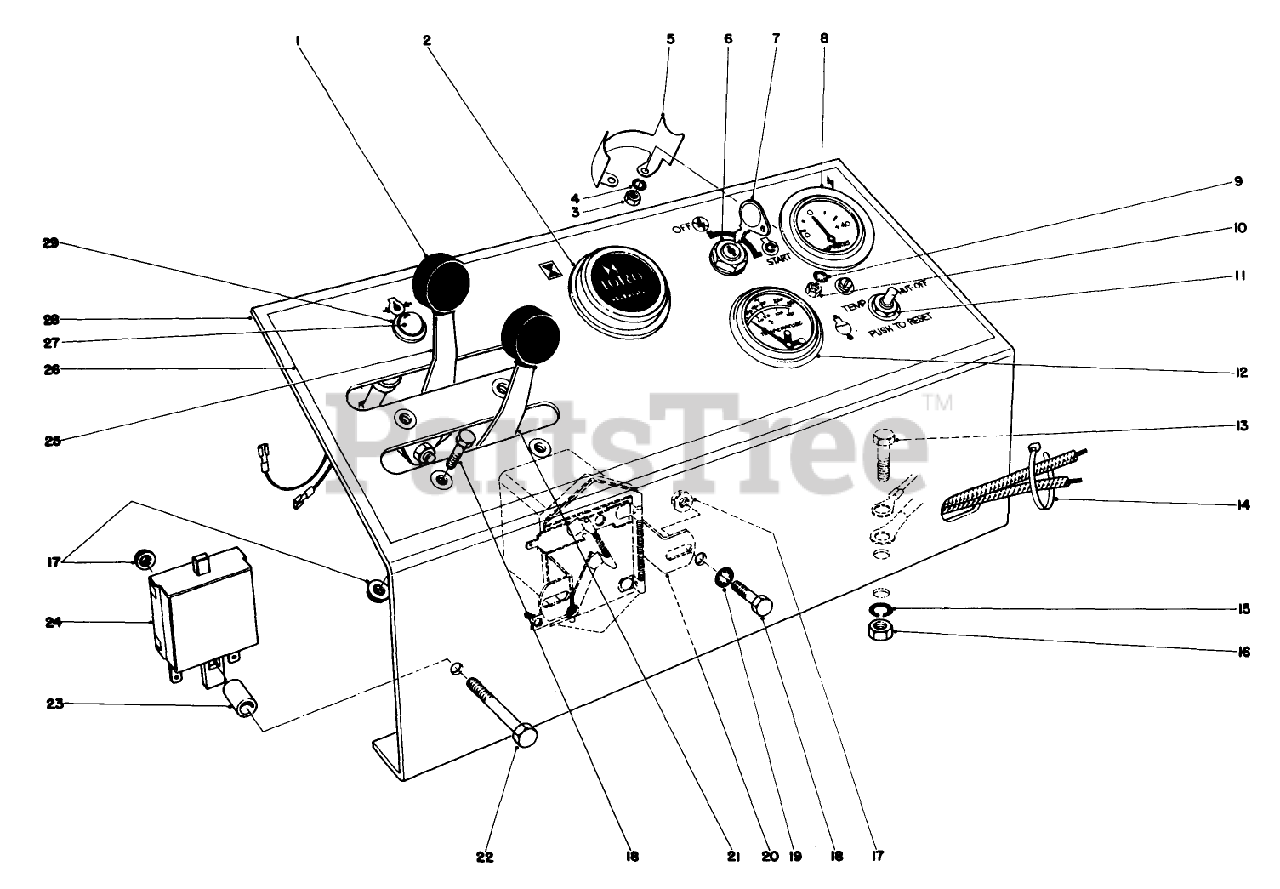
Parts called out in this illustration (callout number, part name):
2	HOUR METER
3	NUT-HEX
4	WASHER-LOCK
5	Clamp
6	SWITCH
7	Key
8	Ammeter
9	WASHER-LOCK, INTERNAL
10	NUT-HEX
11	TEMP RESET RELAY
12	ENG TEMP SWITCH GAGE
13	SCREW-HH
14	TIE-CABLE
15	WASHER-LOCK
16	NUT-HEX
17	NUT-LOCK, FLANGE
19	WASHER-LOCK, INT
20	Regulator
21	Throttle Control (Incl. Ref. #1)
22	SCREW-HH
23	SPACER
24	BUZZER ASM
25	Choke Control (Incl. Ref. #1)
26	Decal-Instrument Panel
27	LENS ASM
28	INST PANEL B
29	Warning Light
